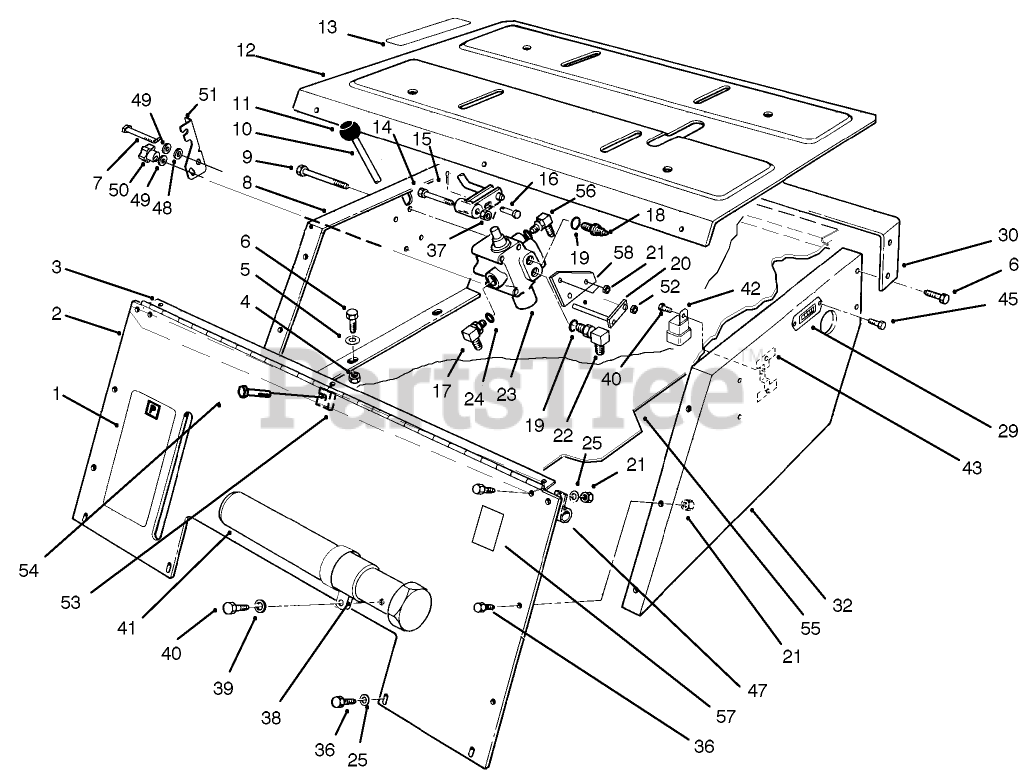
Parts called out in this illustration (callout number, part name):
1	DECAL - PARKING BRAKE
2	Support-Seat, Front
3	Hinge-Seat
4	NUT-LOCK, NI
5	WASHER-PLAIN
6	SCREW-HH
7	SCREW-HH
8	Support-Seat RH.
9	SCREW-HH
10	Lever-Valve
12	Plate-Seat
13	DECAL - LIFT CONTROL
14	BOLT-WHEEL
15	PIN-COTTER
16	PIN-CLEVIS
17	FITTING-HYD, 90 DEG
18	FITTING-STRAIGHT
19	O-RING
20	WA - CONTROL BLOCK
21	NUT-LOCK, NI
22	FITTING-ELBOW, 90
23	VALVE ASM
24	O-RING
25	WASHER-FLAT
29	HOURMETER
30	Support-Hood
32	Support-Seat L.H.
36	SCREW-HH
37	NUT-HEX
38	CLAMP-R
39	WASHER-FLAT
40	SCREW-HWH
41	TUBE-MANUAL
42	RELAY
43	Bracket
45	SCREW-HWH
47	CLAMP-R
48	SPACER - LATCH
49	WASHER-FLAT
50	KNOB-CHUTE
51	BRACKET - HYDRO LOCK
52	NUT-LOCK, NI
53	NUT-SPEED
54	SCREW-HH
55	Cover-Belt
56	FITTING-ELBOW, 90 DEG
57	DECAL-PROTECTION, EAR
58	LEVER BRACKET
